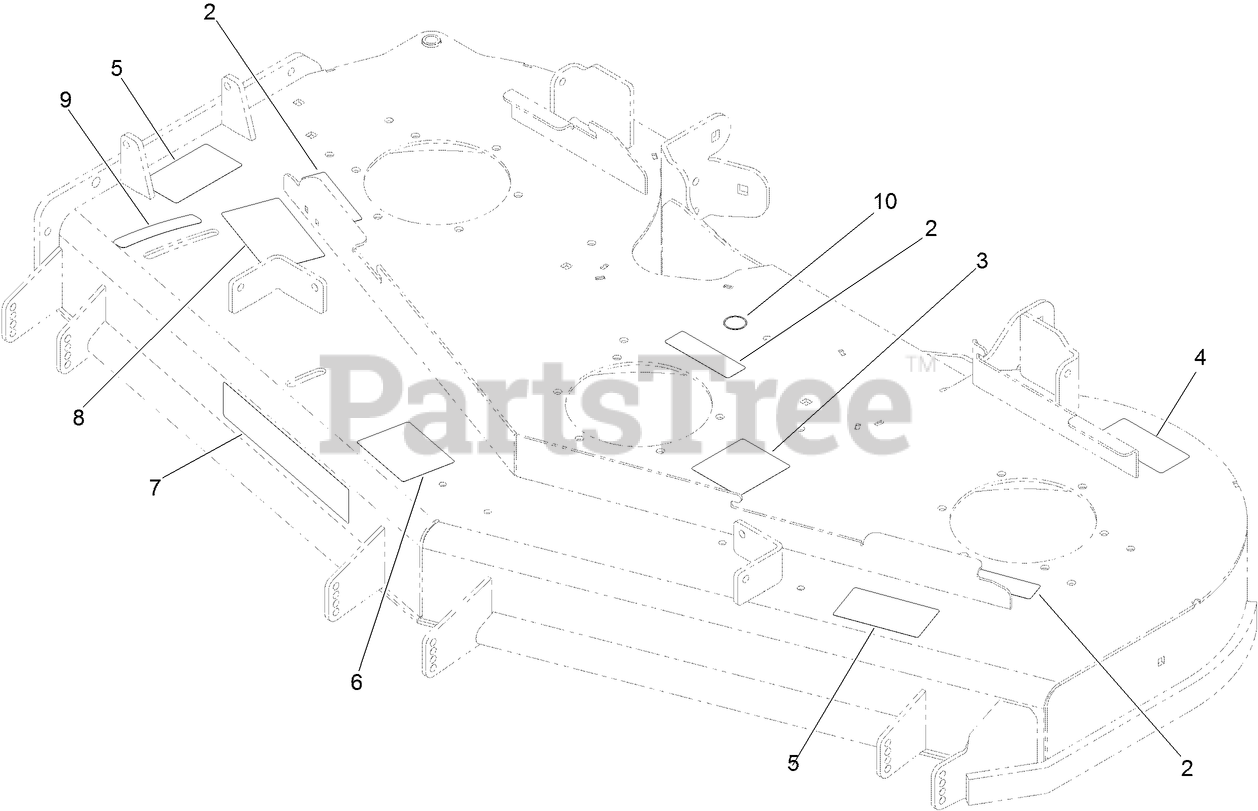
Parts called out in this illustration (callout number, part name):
2	DECAL-MISSING, COVER
3	DECAL-ROUTING, DECK BELT
4	DECAL-TORQUE, BLADE BOLT
5	DECAL-DANGER
6	DECAL-ANTI SCALP
8	DECAL-ADJUSTMENT, BAFFLE
9	DECAL-SETTING, BAFFLE
10	DECAL-GREASE
